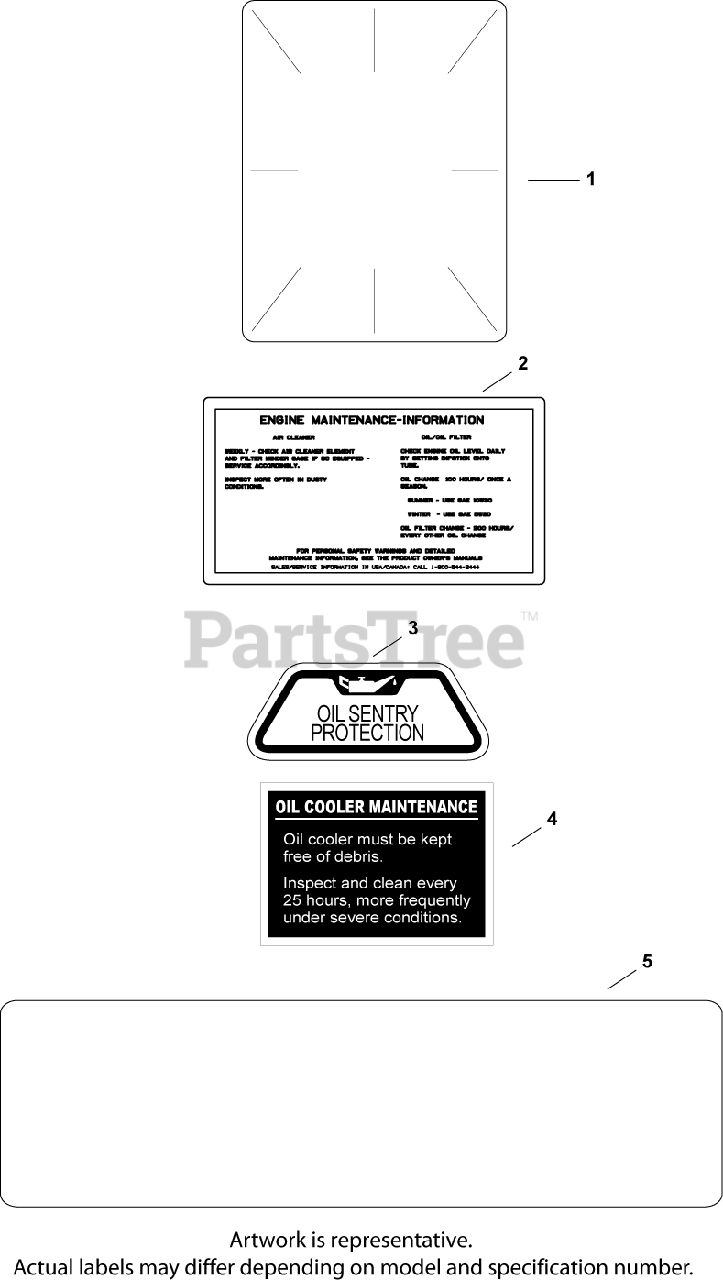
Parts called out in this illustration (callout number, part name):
1	DECAL, CLEAR LAMINATE USE 25 113 70-S
2	DECAL, AIR CLEANER - (#DSC)
3	DECAL, OIL SENTRY - (#DSC)
4	DECAL, OIL COOLER - (#DSC)
5	DECAL, 20 HP
